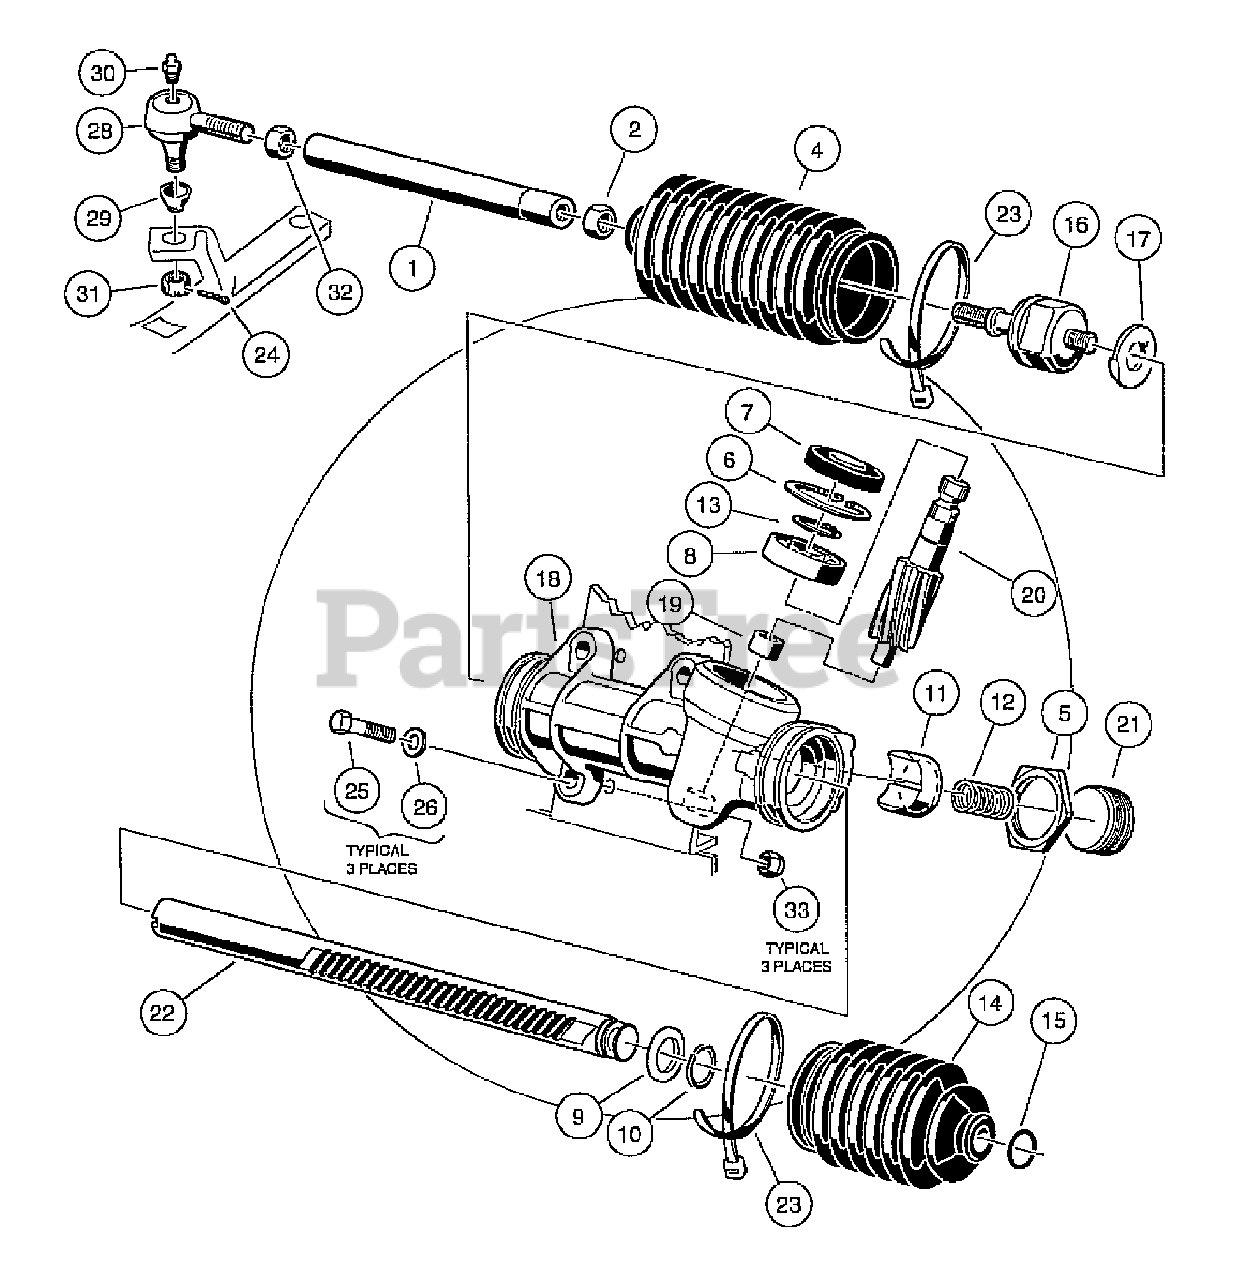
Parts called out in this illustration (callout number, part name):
1	Link, Rack and Pinion Drag
2	Nut, 12mm Hex
3	Steering Gear Assembly (without Yoke)
4	Bellows, Long
5	Rack Screw Locknut
7	Seal, Steering Pinion Dust
8	Bearing, Ball
9	Stop Washer
10	Stop Ring, C-Type
11	Support Yoke
12	Rack Guide Pressure Spring
13	Ring, Stop, C-Type
14	Bellows, Short
15	Dust Seal Retaining Ring
16	Inner Ball Joint Asm
17	Washer, Tab
18	Box, Steering Gear
19	Bearing, Lower Pinion
20	Pinion, Steering
21	Screw, Rack Guide
22	Rack, Steering
23	Tie Wrap, 8" Nylon
24	Pin, 3132 X 1.00 Sq Cut Cotter
25	Screw, 3/8-16 X 1.50 Hx Hd Cap
26	Washer, 3/8 Type A Flat
27	Ball Joint, Left
28	Socket, LH Vertical
29	Seal, Vertical Socket Dust
30	Fitting, 1/4-28 Thread-Forming Grease
31	Nut, 3/8-24 UNF Hex
32	Nut, 1/2-20 Hex, Left-Hand Thread
33	Locknut, 3/8-16 Hex
